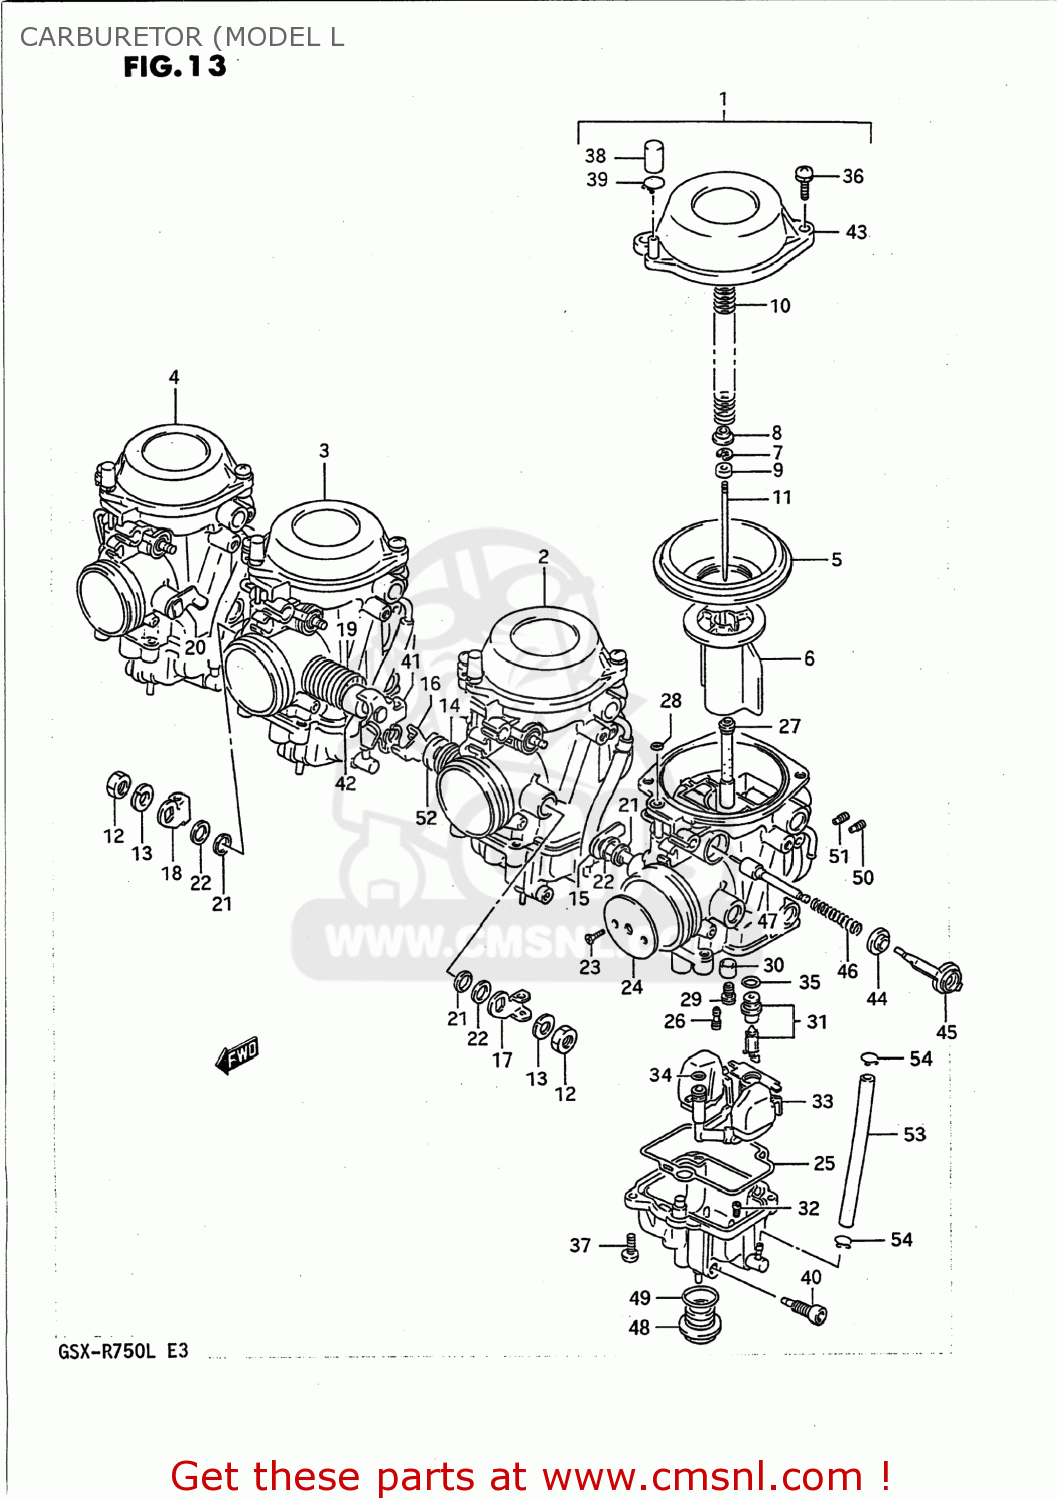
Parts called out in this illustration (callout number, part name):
1	CARBURETOR ASSEMBLY,LEFT
2	CARBURETOR ASSEMBLY,MIDDLE,LEFT
3	CARBURETOR ASSEMBLY,MIDDLE,RIGHT
4	CARBURETOR ASSEMBLY,RIGHT
5	DIAPHRAGM
6	VALVE,PISTON
7	CLIP,NEEDLE
8	WASHER
9	RING
10	SPRING
11	NEEDLE,JET
12	NUT
13	WASHER,LOCK,8.
14	SPRING
15	SHAFT ASSEMBLY
16	SHAFT ASSEMBLY
17	LEVER
18	LEVER,THROTTLE
19	SPRING
20	SHAFT ASSEMBLY
21	SEAL
22	GASKET,THROTTLE SHAFT (NAS)
23	SCREW
24	VALVE,THROTTLE
25	GASKET,FLOAT CHAMBER (NAS)
26	JET,PILOT(32.5)
27	JET,NEEDLE(O-8)
28	O RING
29	JET,MAIN(127.5)
30	RING
31	VALVE ASSEMBLY,NEEDLE
32	PLUG
33	FLOAT ASSY
34	O RING
35	O-RING,NEEDLE VALVE
36	SCREW
37	SCREW
38	CAP
39	CLIP
40	PLUG
41	SHAFT ASSEMBLY
42	RING
43	COVER,DIAPHRAGM
44	CAP,STARTER
45	HOLDER,GUIDE
46	SPRING
47	PLUNGER ASSY
48	SCREW,GUIDE
49	O RING,DRAIN PLUG
50	JET,AIR(1.2)
51	JET,AIR(1.2)
52	RING
53	HOSE
54	CLIP
